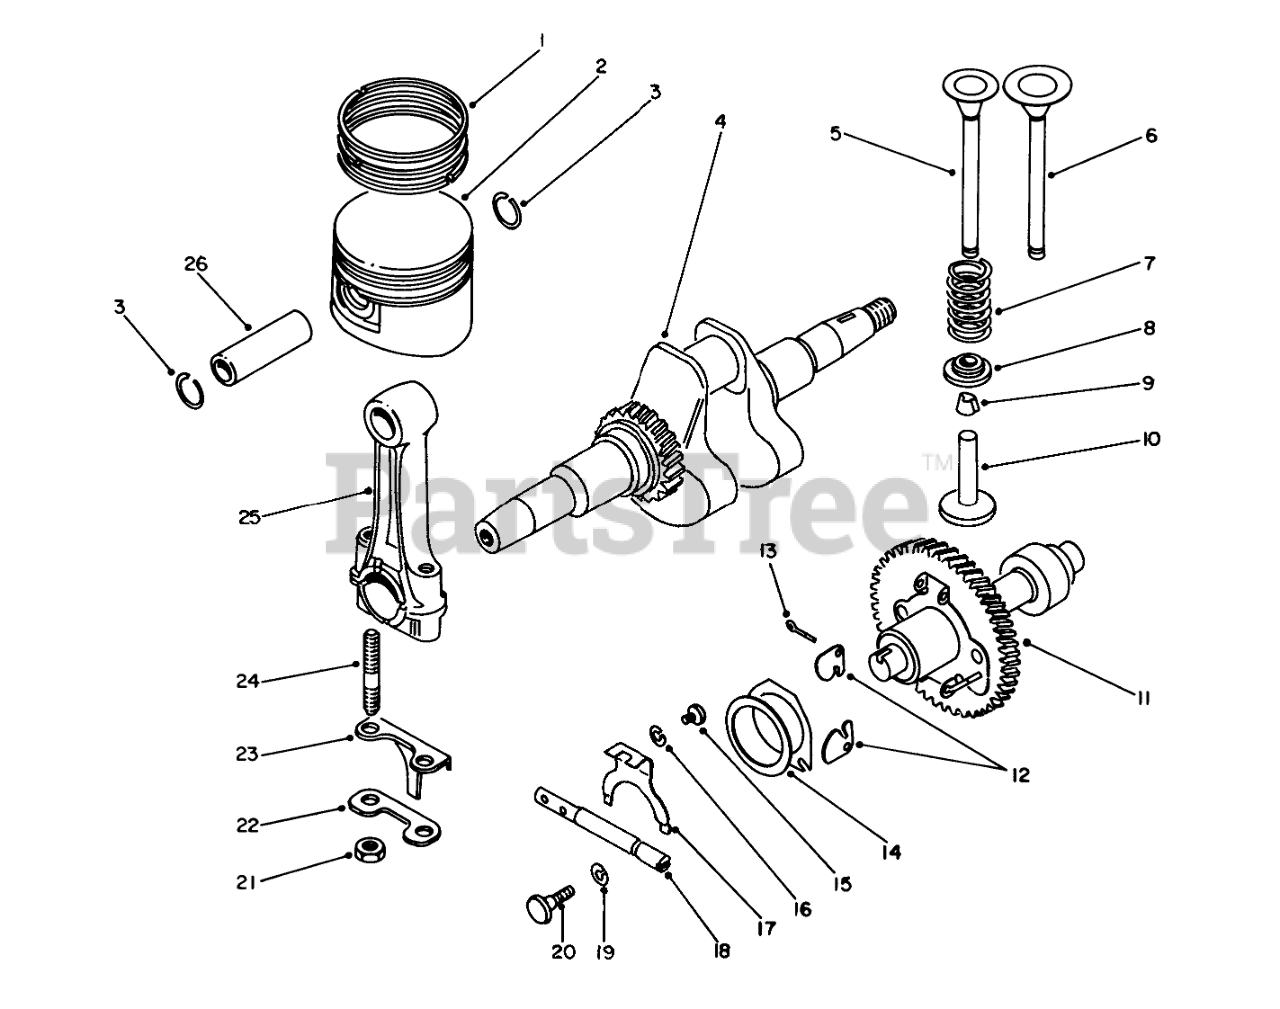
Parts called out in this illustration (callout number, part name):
1	Ring Set
2	Piston
3	Circlip
4	Crankshaft
5	EXHAUST VALVE
6	Valve-Intake
7	Spring
8	Retainer
9	Cotter
10	Tappet
11	Camshaft
13	Cotter Pin
14	Spacer
15	Screw
16	Lockwasher
17	PLATE
18	Shaft
19	Gasket
20	Screw
21	Nut
22	LOCK PLATE
23	Plate-Splash
25	Connecting Rod (Incl. Ref. #21-24)
26	PISTON PIN
